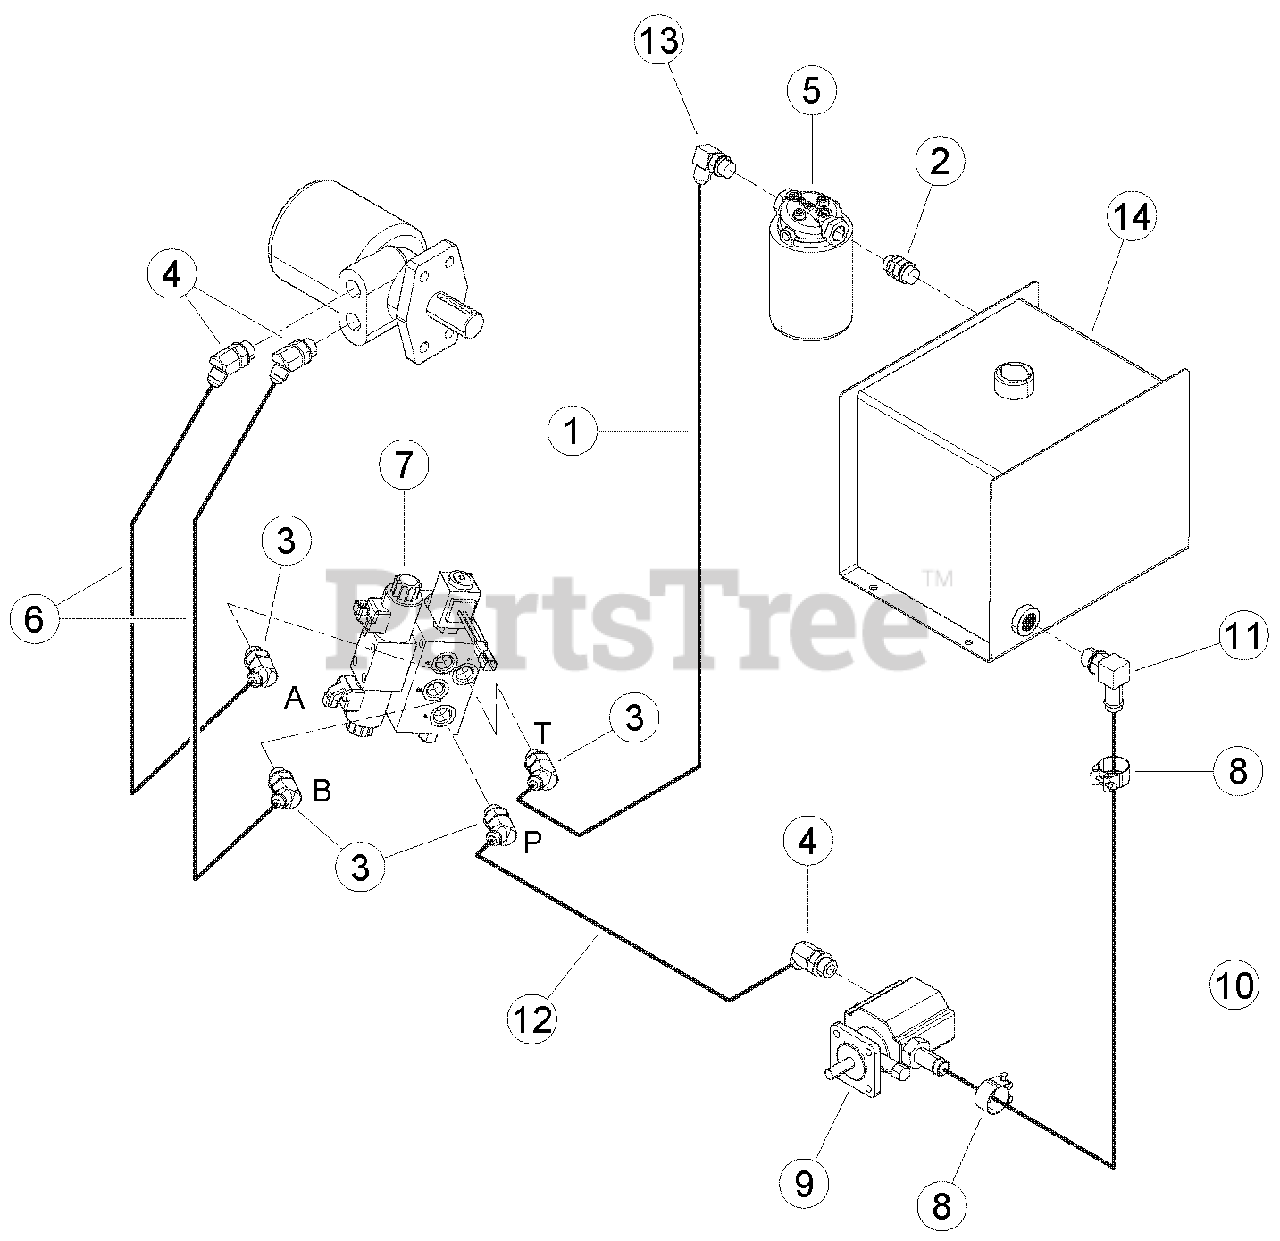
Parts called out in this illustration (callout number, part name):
1	HYD.HOSE ASSY., 2 X -8 FMJICSW (72")
2	ADAPTER, -8 MORING / -8 MORING ADJ
3	ADAPTER, -8 MORB / -8 MJIC 45 DEG.
4	ADAPTER, -10 MORING / -8 MJIC 45 DEG.
5	FILTER, SPIN-ON
6	HOSE, .375 X 36 -8FMJIC/-8FMJIC
7	ASSEMBLY, CHIPPER VALVE
8	CLAMP, 1-5/32 TO 7/32 OD RANGE T-BOLT
9	PUMP, 2 STAGE CW HI/LO 0.605 DISP.
10	HOSE, .75 ID X 24 IN. 100R4 HYD
11	ADAPTER, -10 MORING / .75 90 DEG. HOSE
12	HOSE, .50 X 48 -8 FMJIC / -8 FMJIC
13	ADAPTER, -8 MORING / -8 MJIC 90 DEG.
14	WELDMENT, TANK HYDRAULIC 3.25 GAL.
